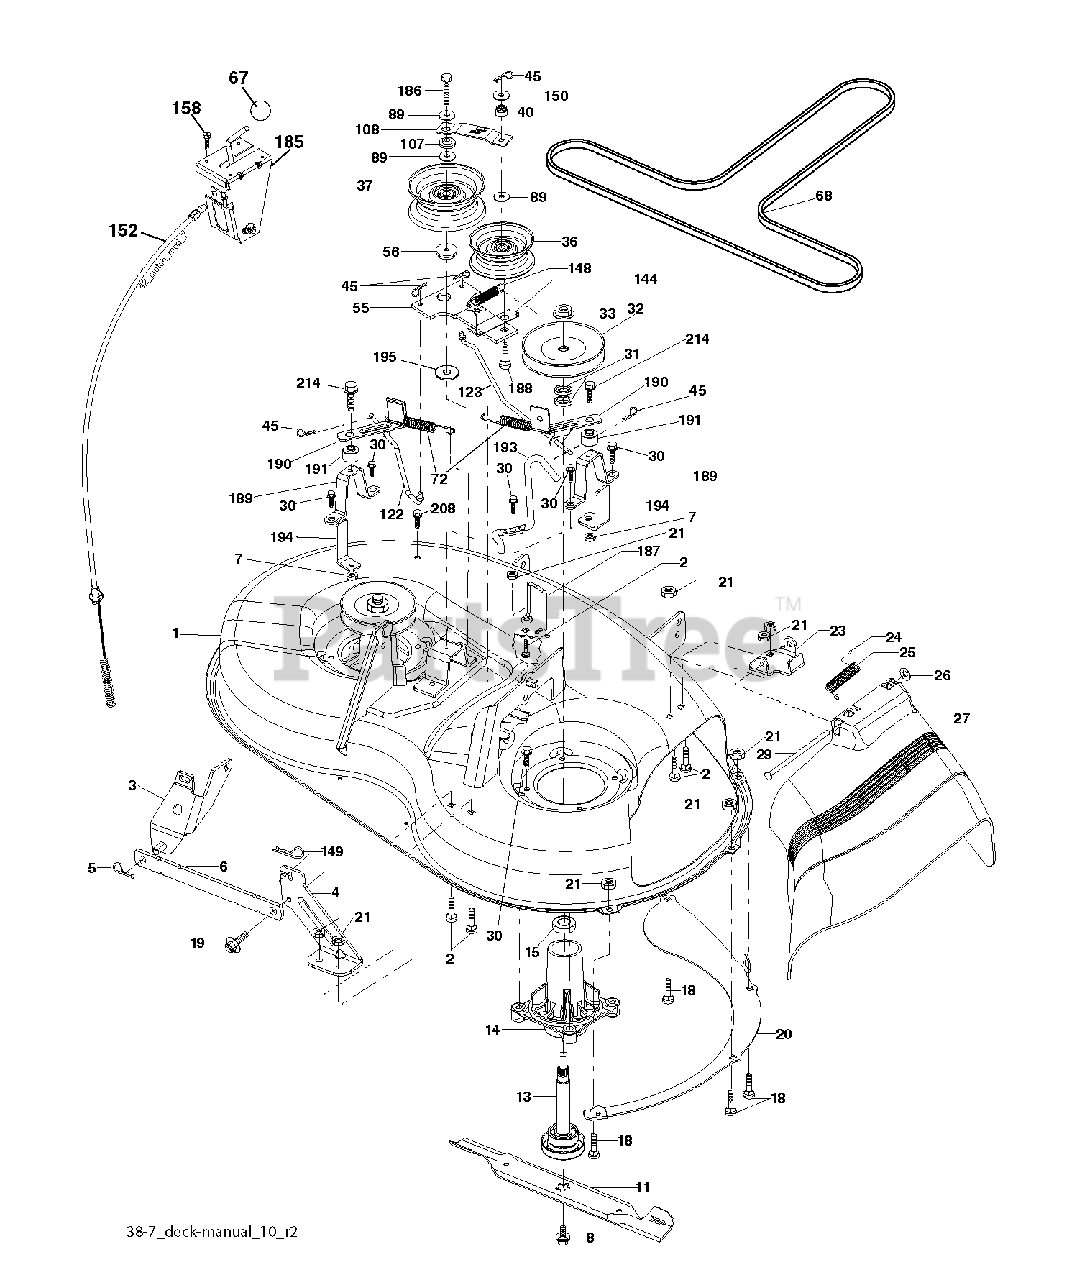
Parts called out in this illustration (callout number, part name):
1	DECK.WELDMENT.38"2005
2	BOLT
3	BRKT ASM SWAY BAR
4	BRACKET DECK SWAY BAR 38"/42"
5	RETAINER-SPRNG RB
6	BAR SWAY DECK
7	NUT.71038.31-18.HEX.NYLOCK
8	BOLT.WASHER.ASM.7/16-2
11	BLADE 38" PREMIUM
13	SHAFT.ASM.MDRL.N/GREASE.38
14	HOUSING MANDREL
18	BOLT
19	BOLT SHD 5/16-18
20	BAFFLE VORTEX
21	LOCKNUT
23	BRKT.DEFLECTOR.38"2005+
24	CAP-SLEEVE LT
25	SPRING.TORSION.DEFLECT
26	NUT PUSH M
29	ROD.HINGE
30	SCREW, WASHER HEAD
31	WASHER.SPACER.MANDREL
32	PULLEY MANDREL
33	NUT.FLANGE.LOCK.TOP
36	FLAT IDLER PULLEY
37	PULLEY.IDLER.FLAT.UNPLATED
40	LOCKNUT
45	RETAINER M
55	IDLER ARM
56	SPACER.RETAINER.MOWER
67	KNOB T (3/8 HOLE)
68	V-BELT.MOWER.38"2005+
72	SPRING.BRAKE.RETURN.38"
89	WASHER
107	SPACER.IDLER.ARM
108	STIFFENER.IDLER.ARM
122	ROD, BRAKE LH LINK
123	LINK.BRAKE.38"RIGHT
144	KEEPER BELT
148	IDLER RETURN SPRING
149	SPRING.RETAINER.YELLOW.ZINC
150	WASHER LT
152	CABLE.CLUTCH.38".SERVICE
158	SCREW
185	HEAD ASM. CABLE CLUTCH
186	SCREW.HXWSH.3/8
187	KEEPER BELT
188	BOLT, CARRIAGE IDLER
189	STAND, BRAKE
190	ARM, BRAKE
191	SPACER, BRAKE
193	KEEPER BELT RH MANDREL
194	GUARD BRAKE
195	WASHER 12/32X2X10GA
208	SCREW 3/8-16X1/2
214	BOLT/WASHER ASM 5/16-18
